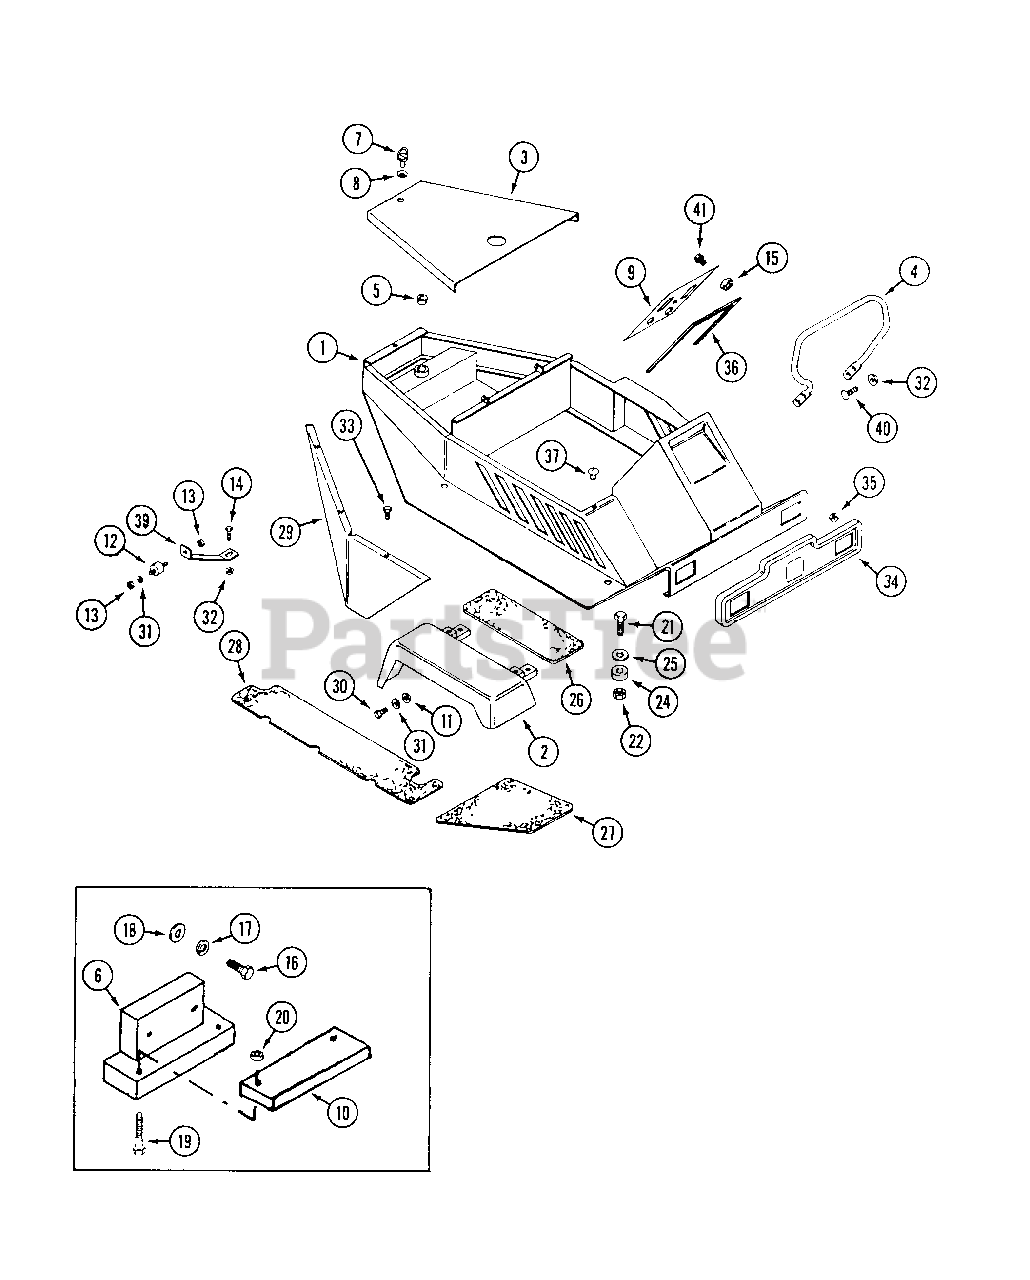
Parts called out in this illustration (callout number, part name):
1	BODY
2	FENDER - R.H.
4	BAR - handle
5	BEARING - rear wheel fork
7	STUD - fastener
8	GROMMET - fastener
10	WEIGHT - tail 13 lb.
11	NUT - flange lock
12	MOUNT - rubber
13	NUT - 1/4" - 20 lock
14	BOLT - 5/16" - 18 x 3/4"
15	NUT - #10 - 24 flange lock
16	BOLT - 5/16" - 18 x 1"
17	LOCKWASHER - 5/16"
18	WASHER - 5/16"
19	BOLT - 3/8" - 16 x 4-1/2"
20	NUT - 3/8" - 16 flange lock
21	BOLT - 1/2" - 13 x 3"
22	NUT - 1/2" lock
24	MOUNT - body, rubber
25	WASHER - mount, body
27	PAD - footrest, front L.H.
27	PAD - footrest, front R.H.
28	PAD - footrest, rear L.H.
30	BOLT - 1/4" - 20 x 3/4"
31	WASHER - 1/4"
32	NUT - 5/16" - 18 flange lock
33	BOLT - 5/16" - 18 x 5/8" black
35	NUT - #8 - 32 flange lock
36	TRIM - 27"
37	BUMPER - nylon
39	BRACKET - fender support
40	BOLT - 5/16" - 18 x 1" carriage
41	SCREW - #12 x 1/2"
